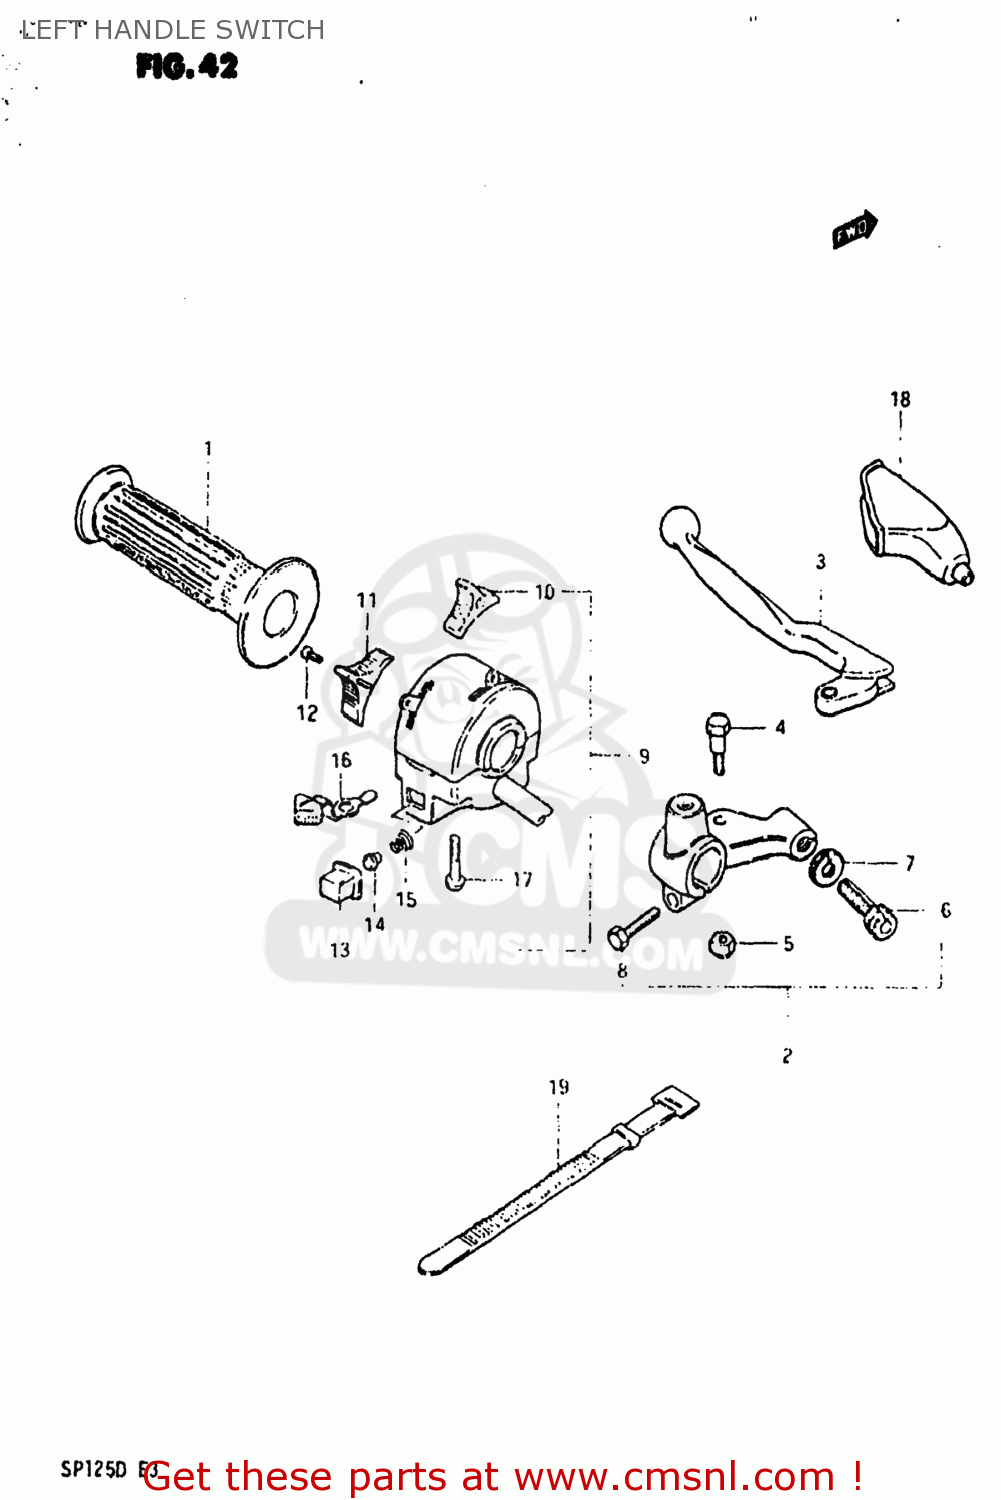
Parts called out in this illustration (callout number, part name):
1	GRIP,L
2	LEVER ASSY,CLUTCH
3	LEVER,CLUTCH
4	BOLT,LEVER
5	NUT 6MM
6	ADJUSTER,CABLE
7	NUT,CABLE ADJUSTER
8	BOLT,CLUTCH LEVER HOLDER
9	SWITCH ASSEMBLY,HANDLE,LEFT
10	KNOB,STOP
11	KNOB,DIMMER SWITCH
12	SCREW
13	BUTTON,HORN
14	CONTACT
15	SPRING
16	KNOB,TURNSIGNAL
17	SCREW
18	COVER,CLUTCH LEVER
19	CLAMP(L:120)
